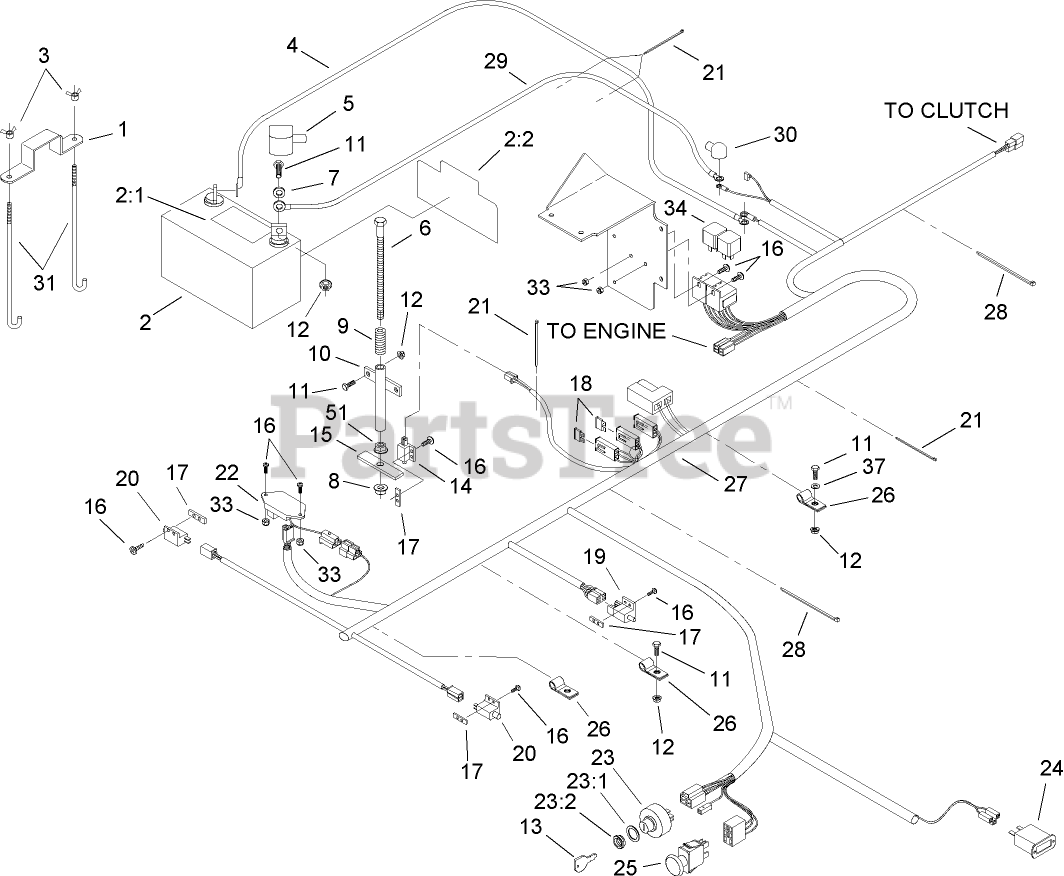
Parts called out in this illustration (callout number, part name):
1	STRAP-HOLDDOWN
2	BATTERY
2:1	Decal-Battery
2:2	Decal-Battery
3	WINGNUT
4	WIRE-GROUND
5	INSULATOR-BATTERY
6	SCREW-HH
7	WASHER-FLAT
8	NUT-LOCK, NI
9	SPRING-SWITCH, SEAT
10	MOUNT-SPRING, SEAT
11	SCREW-HH
12	NUT-HF
13	KEY-IGNITION
14	SWITCH-CLOSED, NORMALLY
15	PLATE-SWITCH, SEAT
16	SCREW-PPH
17	PLATE-TAPPED
18	FUSE-BLADE TYPE, 20 AMP
19	SWITCH
20	SWITCH-OPEN, NORMALLY
21	TIE-CABLE
22	MODULE-DELAY, SEAT
23	Key Switch ASM
23:1	WASHER-TOOTH, INTERNAL
23:2	NUT-HH
24	METER-HOUR
25	SWITCH-DELTA
26	CLIP-LOOM
27	Harness-Wire
28	TIE-PLASTIC
29	WIRE-STARTER
30	INSULATOR-SOLENOID
31	BOLT-HOLDDOWN
33	NUT-LOCK, NI
37	WASHER-FLAT
51	NUT-HEX
